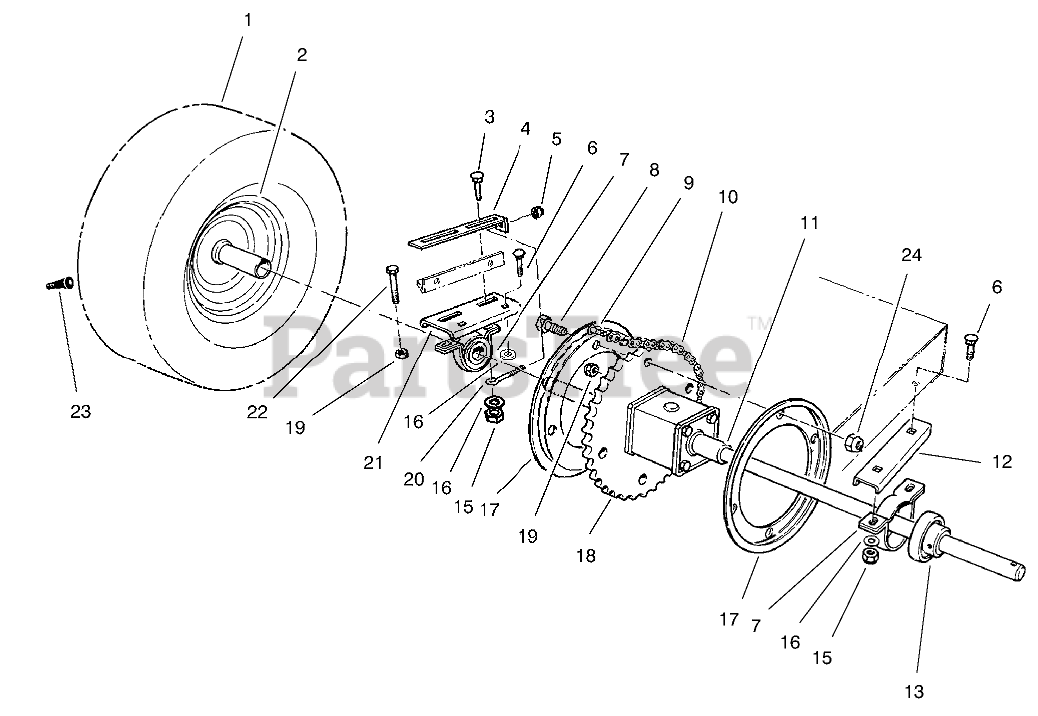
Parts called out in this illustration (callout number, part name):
2	WHEEL-REAR
3	SCREW-CARR
4	PLATE-ADJUSTING
5	NUT-LOCK, NI
6	BOLT-CARR
7	RTNR-PILLOW BLK
8	SCREW-HH
9	LINK-CHAIN
10	Chain (Incl. Ref. #9)
11	DIFFERENTIAL
12	SUPPORT-LH AXLE
13	Bearing (Incl. Ref. #14)
15	NUT-LOCK, NI
16	WASHER-FLAT
17	GUIDE-REAR CHAIN
18	SPROCKET
19	NUT-LOCK, NI
20	SCREW-ADJUSTING
21	RH AXLE SUPPORT (BLACK)
22	AXLE MTG BOLT
23	STEM-VALVE
24	NUT-HEX
